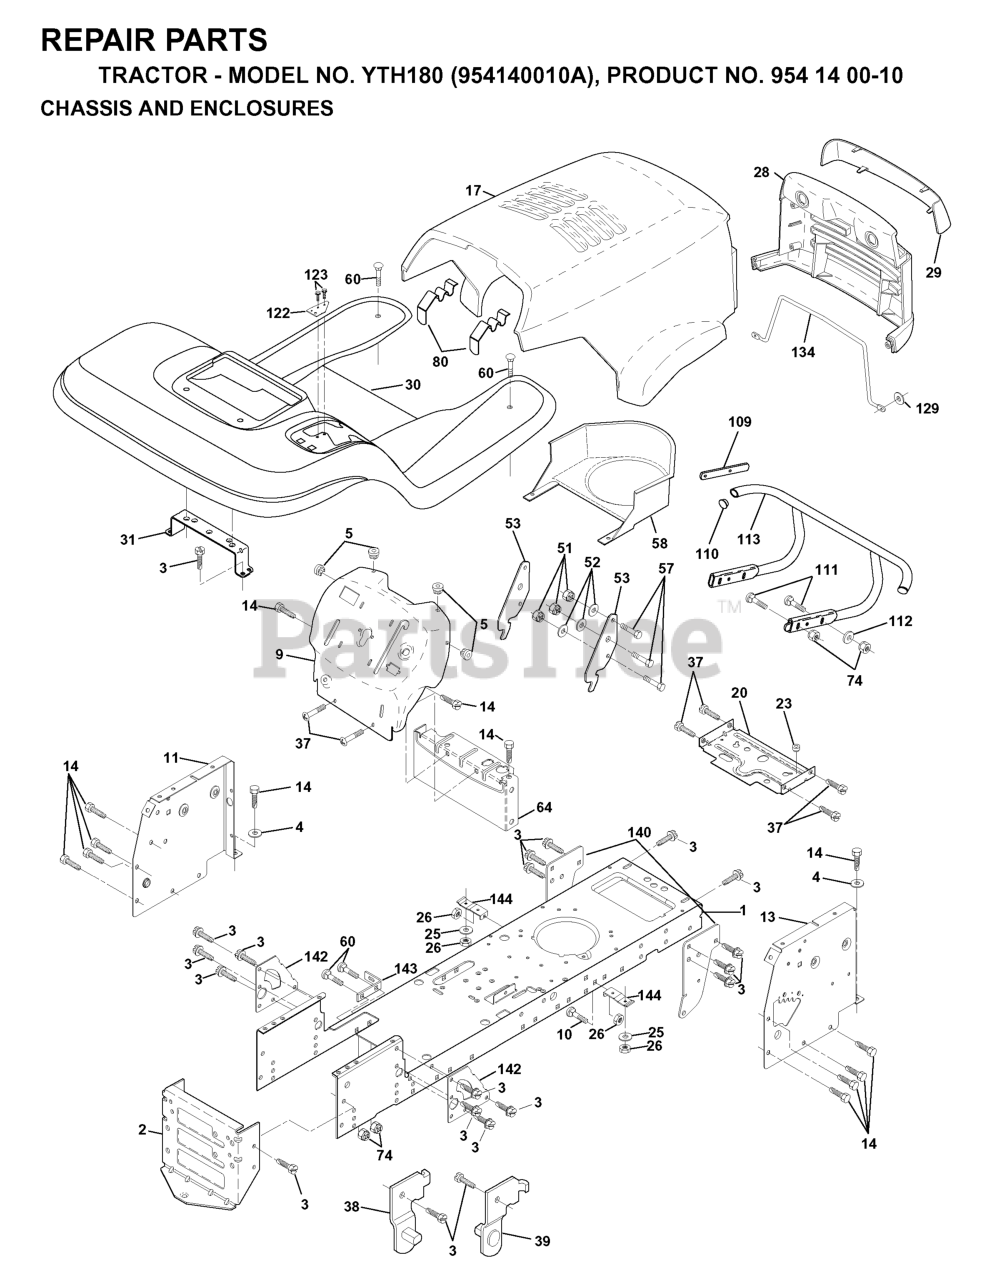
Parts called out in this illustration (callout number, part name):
1	CHASSIS WELDMENT
2	STRETCH DRAWBAR
3	SCREW
4	Washer 13/32 X 3/4 X 16 Ga.
5	BUMPER.RUBBER.HOOD
9	DASH PANEL
10	BOLT D
11	PANEL DASH LH
17	HOOD - LT/YT
20	PLATE MTG
23	BUSHING.SNAP.NYL.BLK.
25	WASHER
26	NUT
28	GRILLE LT/PL HUSQVARNA
29	LENS LT/PL HUSQVARNA
30	FENDER FOOTREST
31	BRACKET.SUPPORT.FENDER
37	Screw 5/16-18 x 1/2 Hex, Self Tapping 5/16-18 x 1/2
38	BRACKET LH PIVOT
39	BRACKET RH PIVOT
51	LOCKNUT.NYLOC.1/4-20
53	BRACKET PNT PICK OFF LT/PL
57	BOLT
60	Bolt - Rd. Hd. Sq. Neckiage 3/8 16 x 3/4
64	DASH LOWER
80	LATCH HOOD
109	BRACKET BUMPER
110	PLUG PLASTIC
111	Bolt, Carriage 3/8-16 UNC x 1-1/2
112	WASHER
122	BRACKET SHIFT STLT
134	ROD SUPPORT HOOD LT/PL HUSQ
140	BRACKET CHASSIS FRONT
142	PLATE REINFORCEMENT
143	BRACKET, SWAY BAR
144	BRACKET FOOTREST
146	SCREW TORX HD 5/16X18
